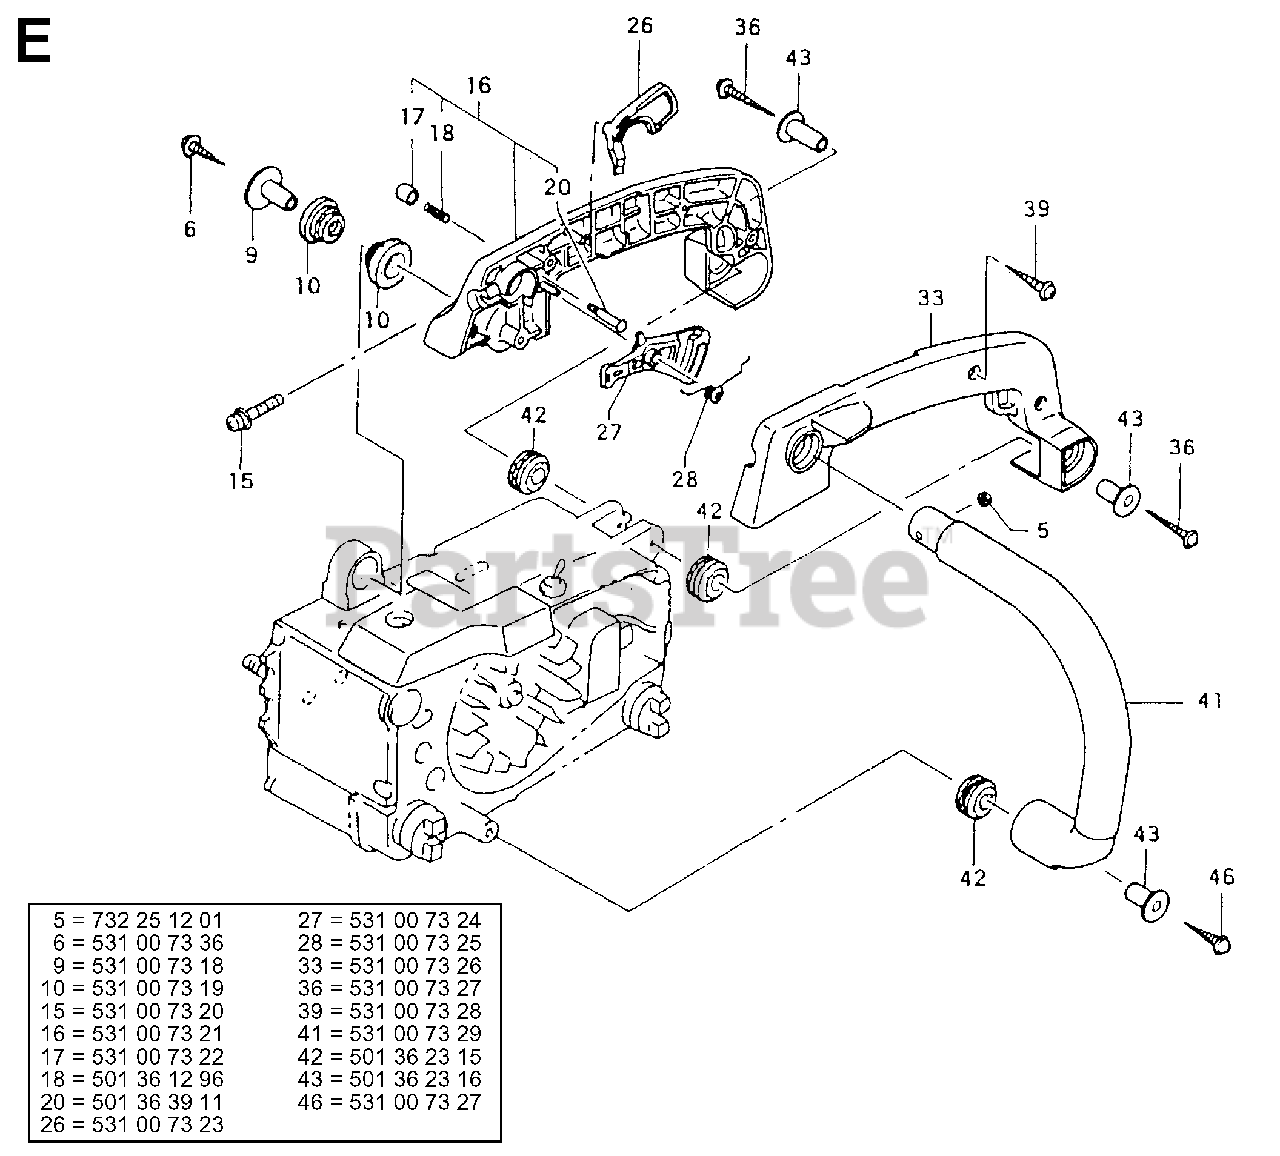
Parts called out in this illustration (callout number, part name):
5	NUT M4
10	VIBRATION ABSORBER
26	THROTTLE LOCK
